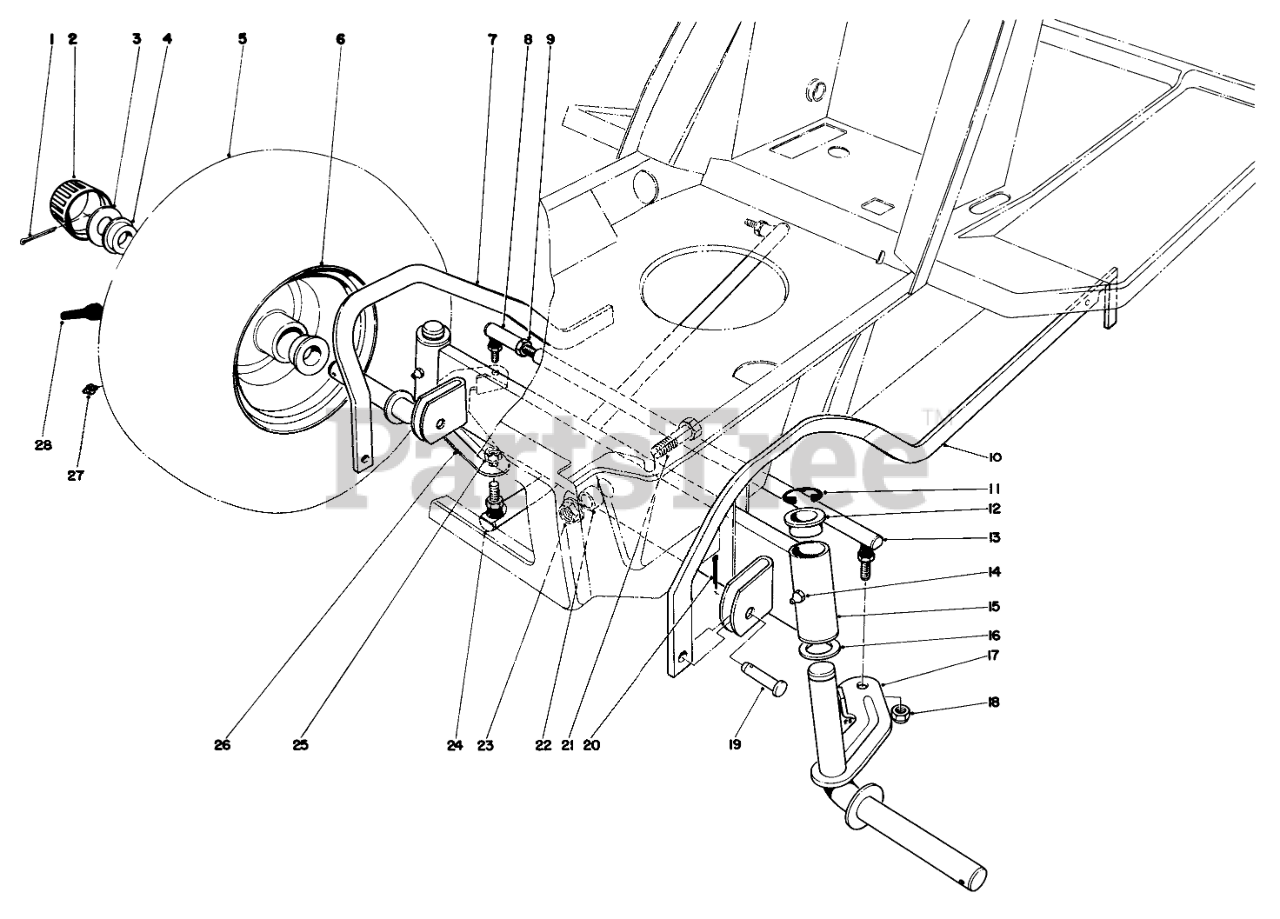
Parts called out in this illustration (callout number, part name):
1	PIN-COTTER
2	Cap-Hub
3	WASHER-PLAIN
4	Bearing
5	TIRE-FRONT
6	FRONT WHEEL
7	RH DECK PARALLEL LINK R
8	JOINT-BALL
9	NUT-JAM
10	LH DECK PARALEL LNKR
11	E-Ring
12	BEARING-FLANGE
13	STEERING ROD
14	Fitting-Grease
15	Front Axle (Incl. Ref. #12)
16	WASHER-THRUST
17	Spindle L.H.
18	NUT-LOCK, NI
19	PIN-CLEVIS
20	PIN-COTTER
21	SCREW-HH
22	SPACER-AXLE, FRONT
23	NUT-HF
24	STEERING ARM B
25	NUT-HEX
26	SPINDLE WA RH B
27	FITTING-GREASE
28	STEM-VALVE
